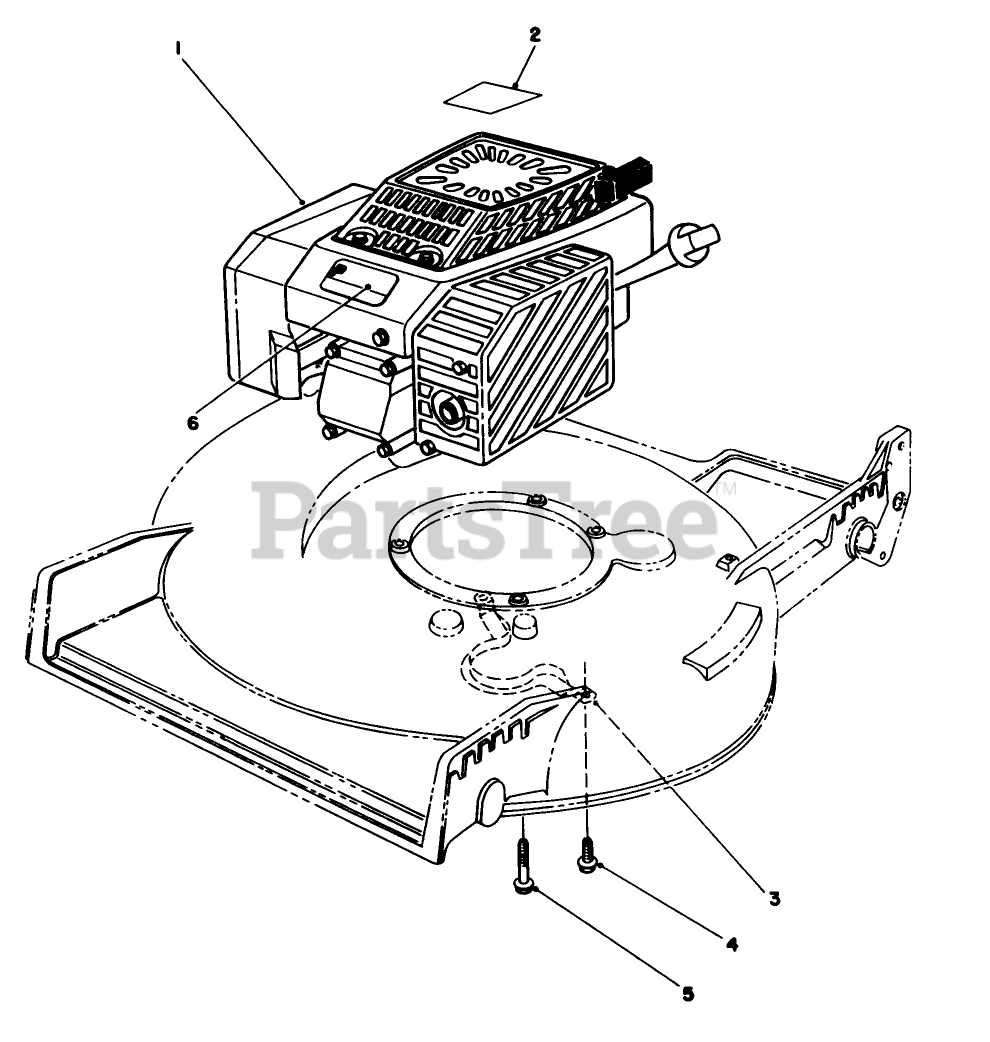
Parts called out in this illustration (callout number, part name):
1	Engine-Complete (Incl. Ref. #2, & 6)
2	DECAL - ENGINE
3	Guide-Belt
4	SCREW-HWHTF
5	SCREW-HWH
6	DECAL - PROLINE
